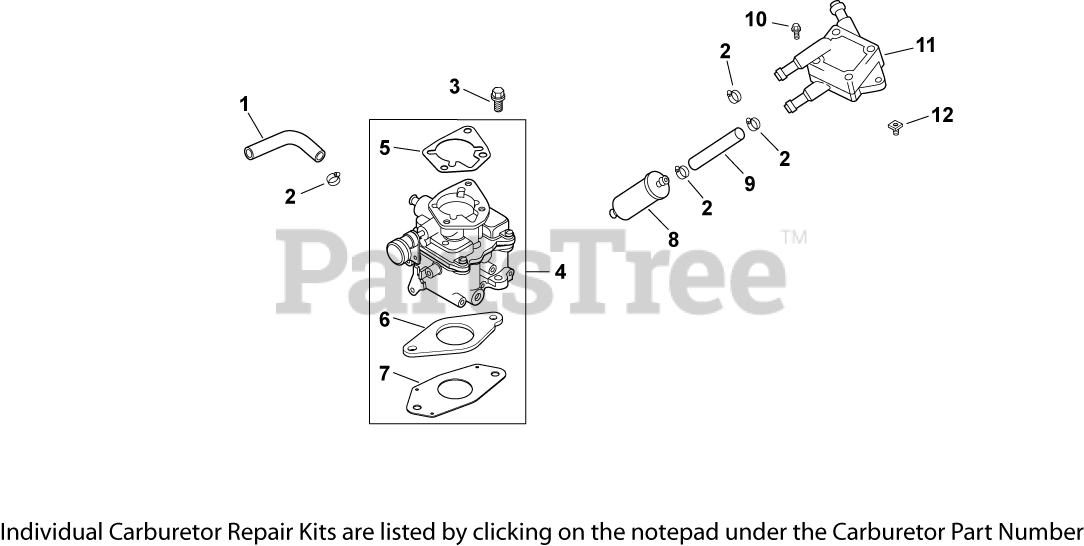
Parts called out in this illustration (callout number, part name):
1	HOSE,LW PERM.FUEL 24.00"-USE 25 111 81-S
2	CLAMP, HOSE (KM)-USE 25 237 31-S
3	SCREW, FLG M6X1.0X25
4	KIT, CARBURETOR W/GASKETS-KSF
5	GASKET, AIR CLEANER BASE
6	GASKET, CARBURETOR
7	GASKET, CARBURETOR
8	FILTER, FUEL
9	LINE, FLEXIBLE FUEL 15 1/2"
10	SCREW, TAP M6X1.7X18
11	PUMP, FUEL
12	NUT, PLASTIC - BLACK
2451824-S	LEAD, GROUND
